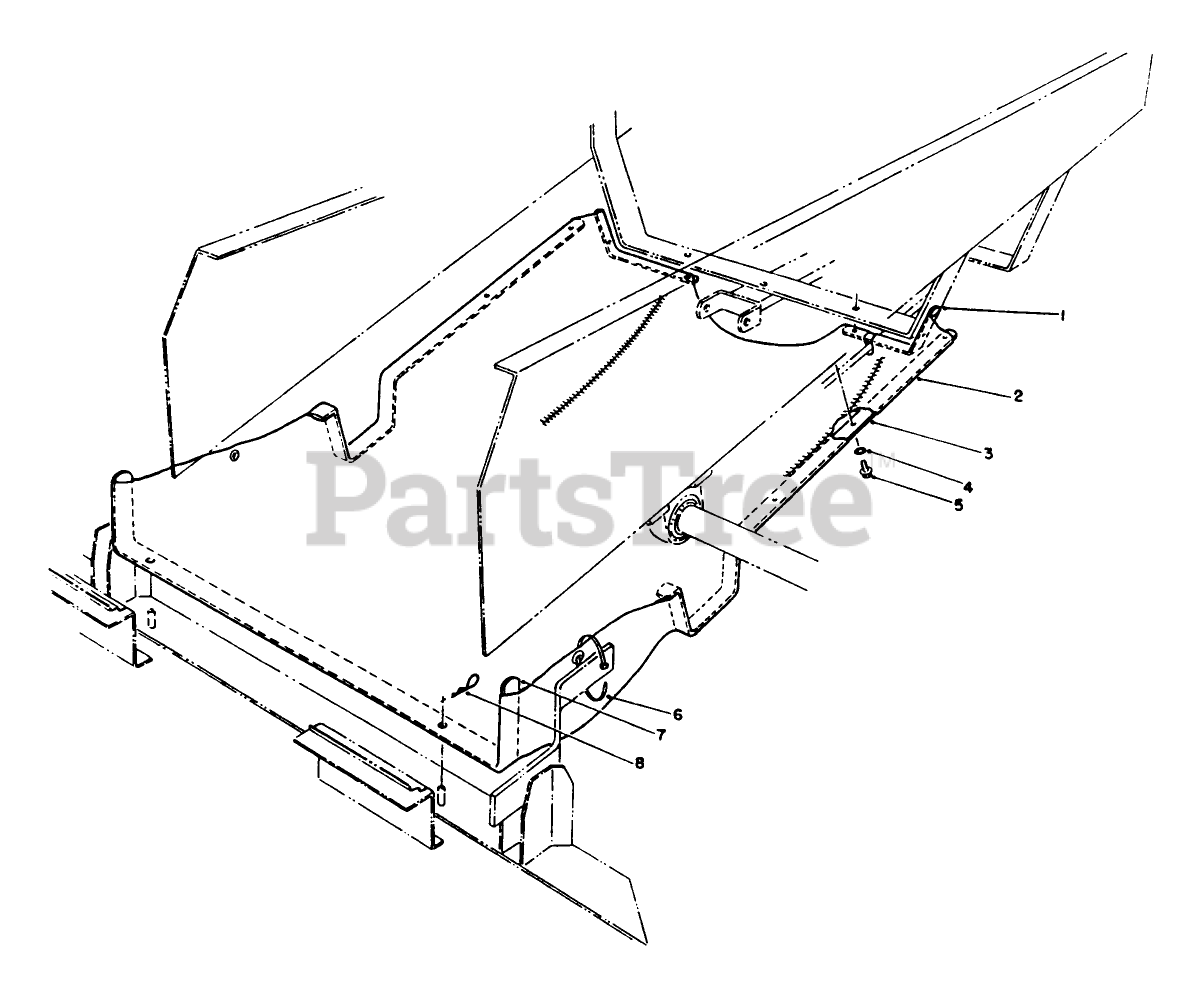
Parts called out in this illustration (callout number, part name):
1	SHIELD BRACKET R
2	CLOTH SHIELD
3	Support-Side
4	WASHER-LOCK
5	SCREW-HWH
6	TIE-CABLE
7	DECK SHIELD SUPPORT R
8	PIN-HAIR
